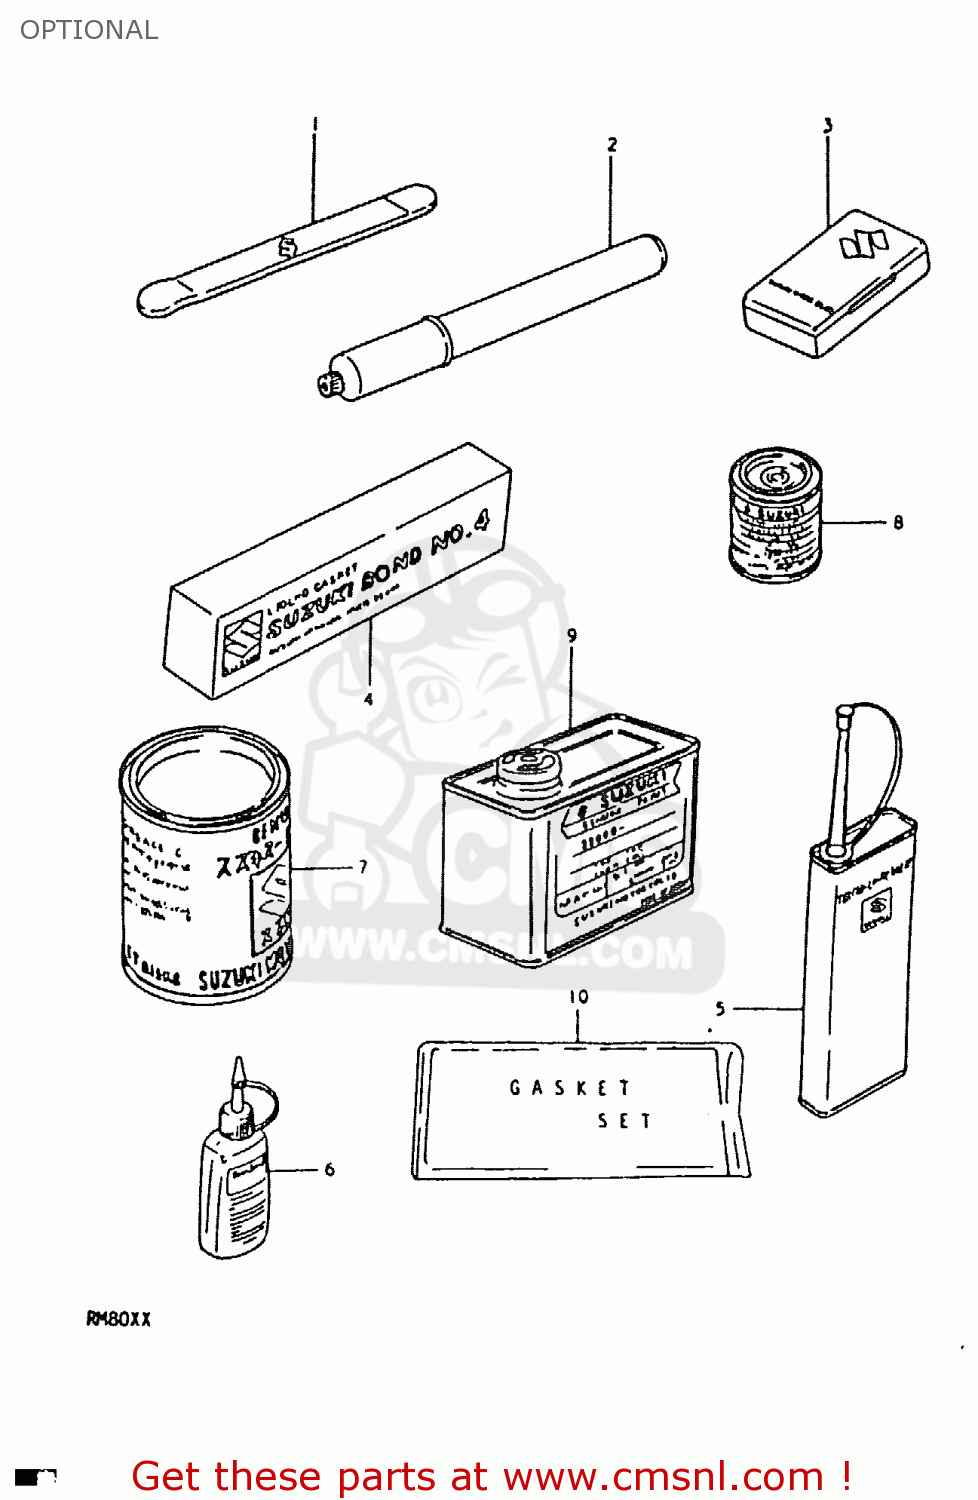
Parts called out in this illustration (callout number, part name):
1	LEVER,TIRE
2	INFLATOR, AIR
3	TUBE REPARING TOOL
4	BOND 1104
5	THREAD LOCK NO.1401 CLEAR 200G
6	THREAD LOCK NO.1303B PURPL 50G
7	GREASE(C)EP2 LITHIUM 150G
8	PAINT,BLACK
9	PAINT (BLACK)
10	GASKET SET (MCA)
